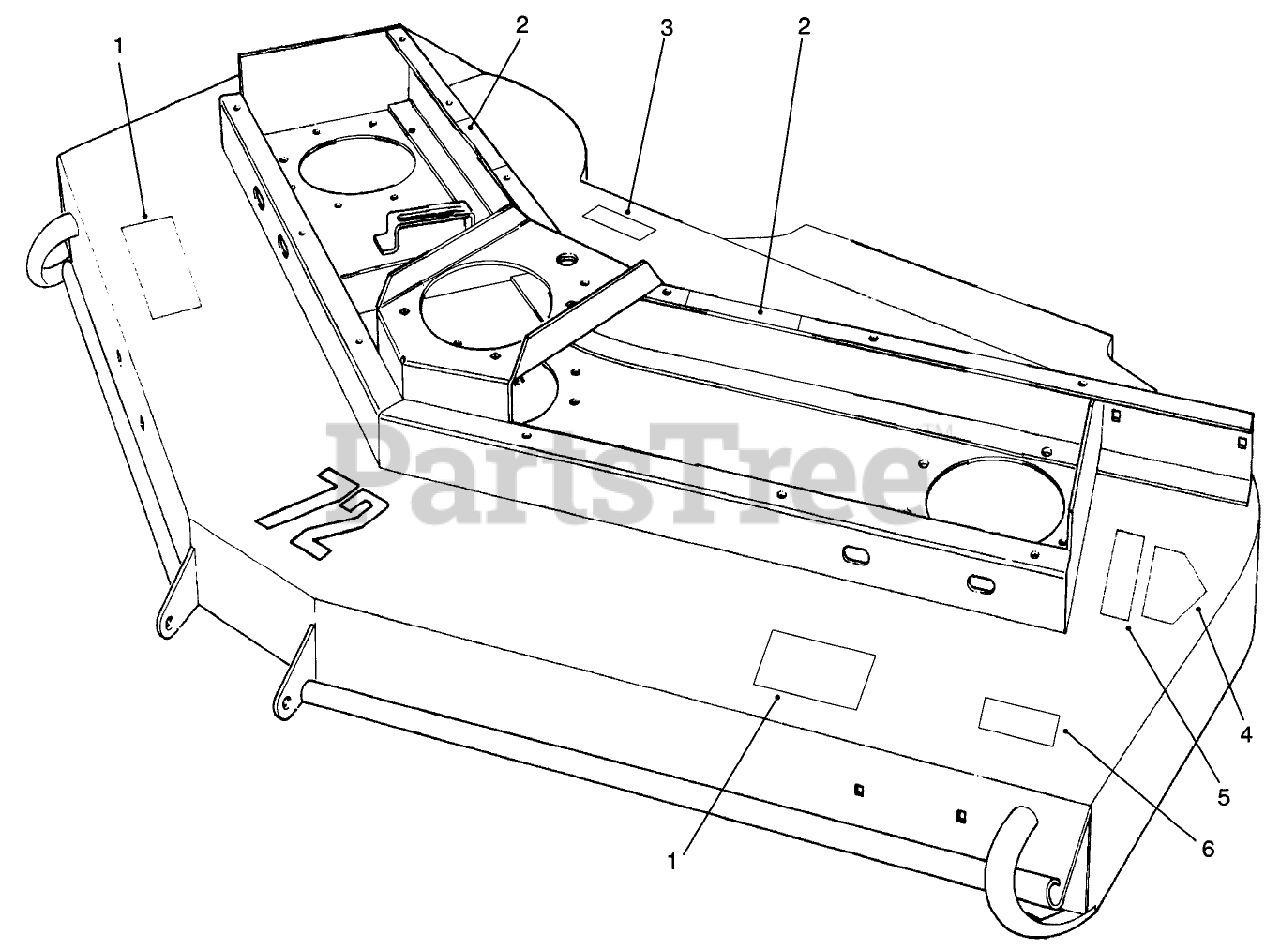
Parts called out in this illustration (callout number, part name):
1	DECAL-DANGER
2	DECAL-DANGER
3	DECAL BLANK
4	DECAL-DANGER, INT'L
5	DECAL-TORQUE, BLADE BOLT
6	DECAL-WARNING
